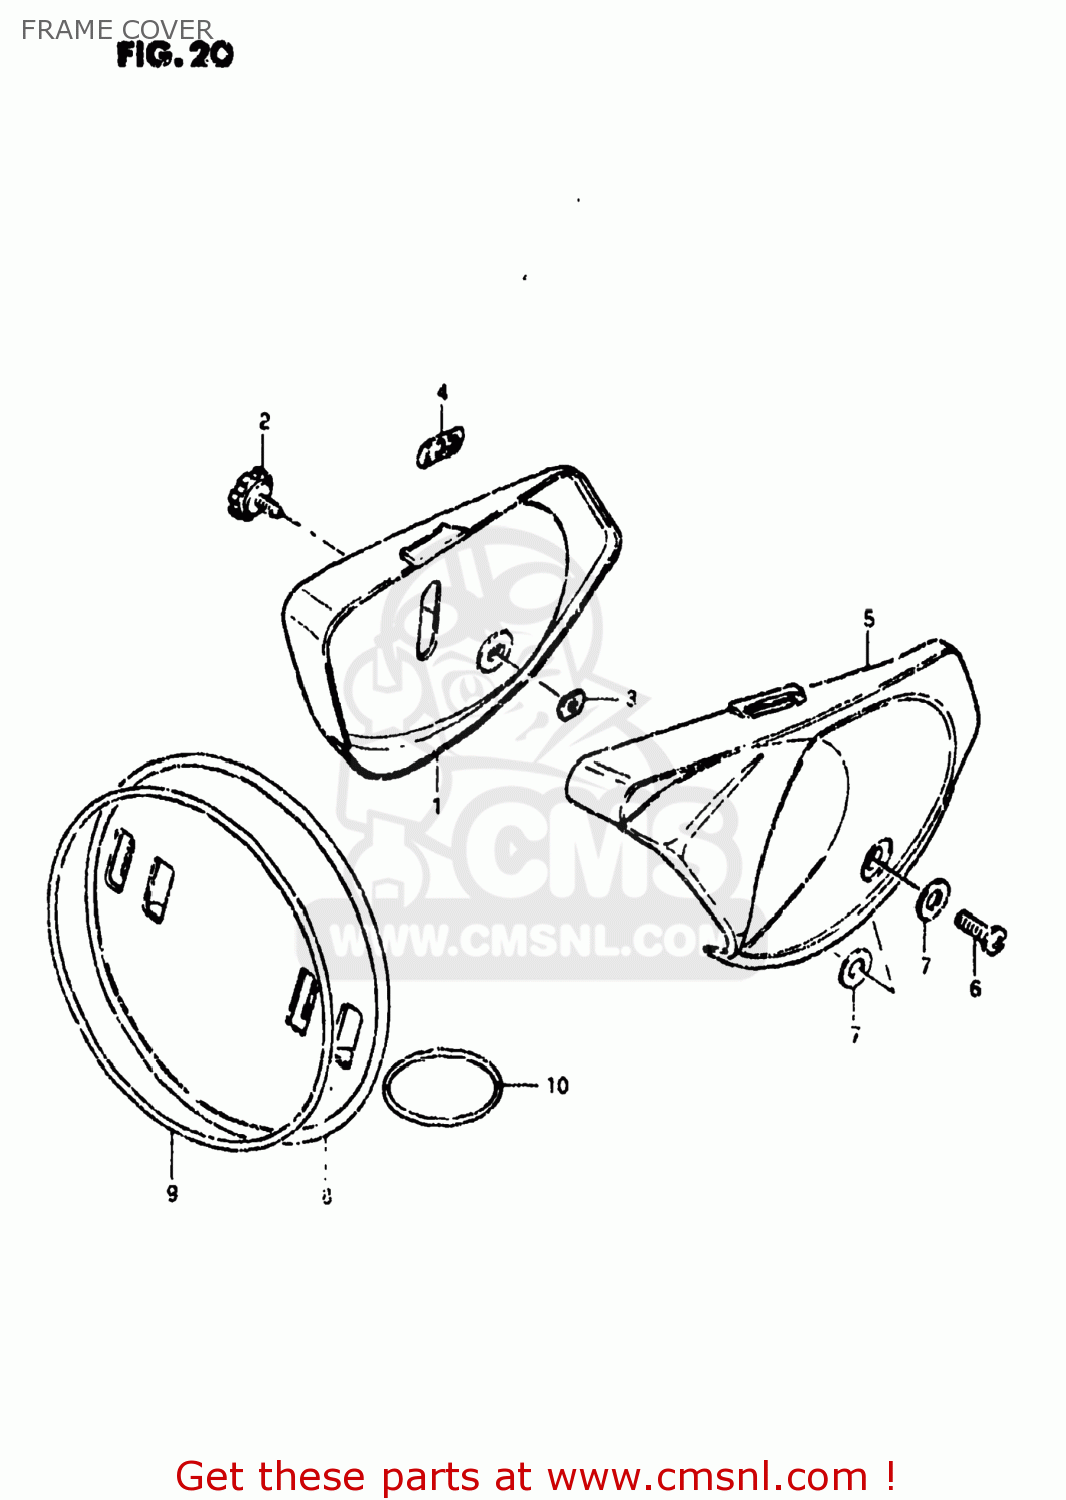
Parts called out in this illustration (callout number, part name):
1	COVER,FRAME,RIGHT
2	KNOB,FRAME COVER,R
3	NUT
4	EMBLEM,CCIS
5	COVER,FRAME,LEFT
6	SCREW 6X12
7	WASHER
8	PLATE,NUMBER,FRONT
9	TAPE,FRAME COVER
10	O-RING
